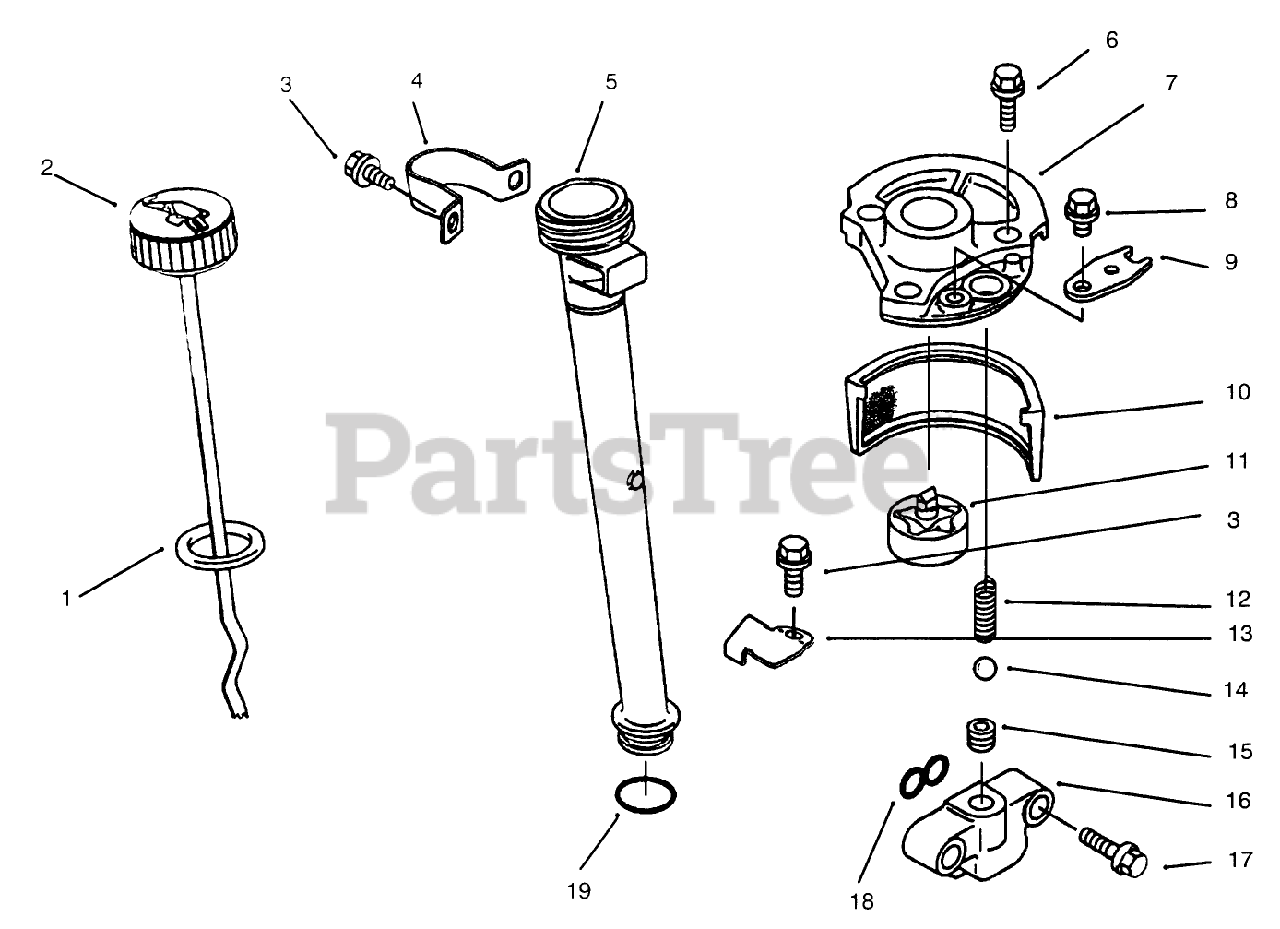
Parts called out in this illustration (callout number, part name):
1	Gasket
2	Gauge
3	Bolt
4	Clamp
5	Filler
6	Bolt-Flanged (8X25)
7	Cover-Pump
8	BOLT-FLANGED (6X10)
9	Plate
10	Filter-Oil
11	Pump ASM-Oil
12	Spring
13	Plate
14	Ball
15	Plug
16	Cover
17	Bolt
18	Seal
19	O-RING (16mm)
